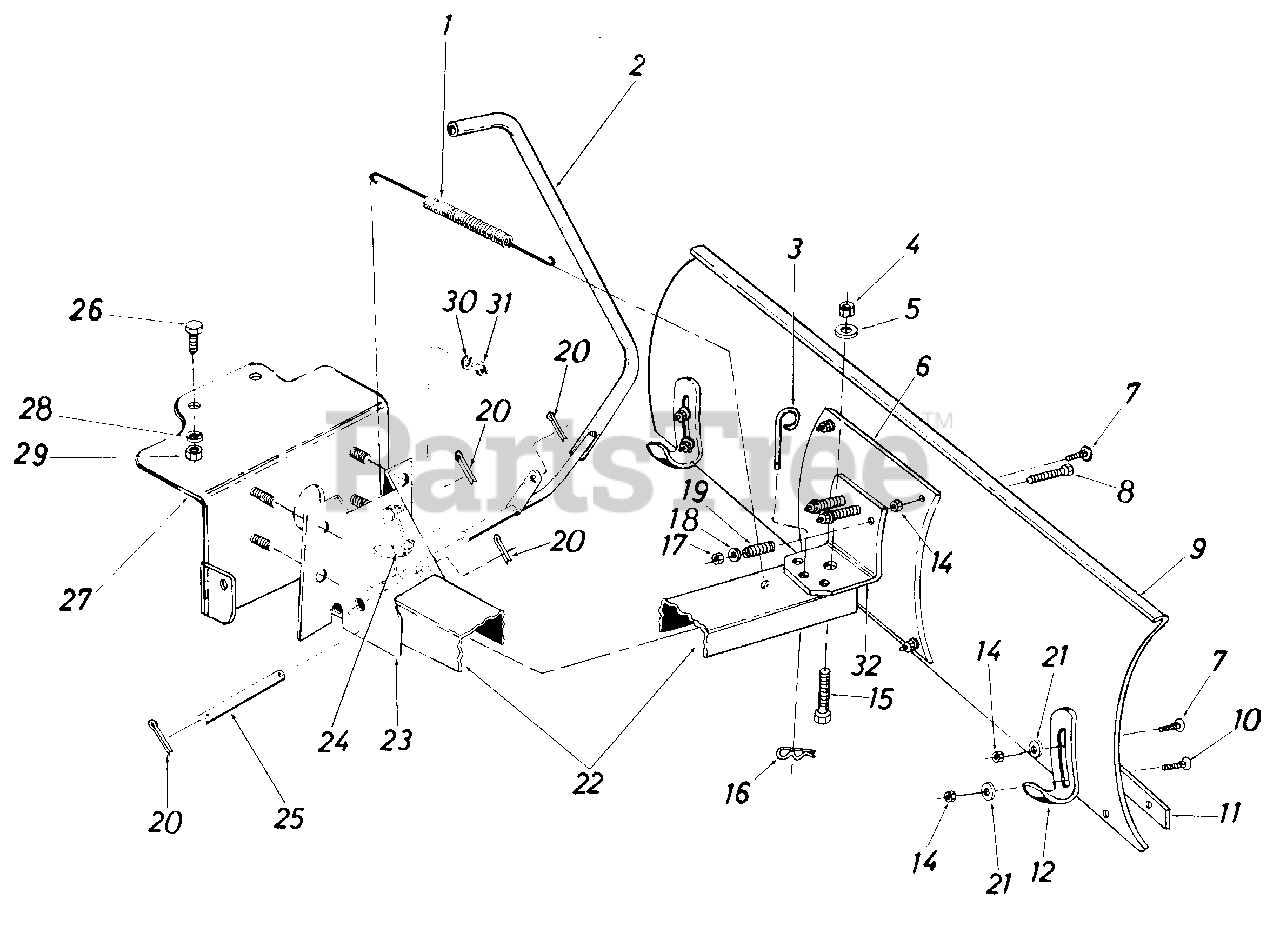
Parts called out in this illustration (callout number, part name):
1	Extension Spring
2	Lift Handle Ass'y.
3	Pivot Lock Pin
4	Hex Cent. L.-Nut 1/2-13 Thd.
5	Fl.-Wash. 17/32 I.D. x 1.25" Lg.
6	Reinforcement Plate
7	Carriage Bolt 5/16-18 x .75" Lg.*
8	Hex Scr. 3/8-16 x 3.75" Lg. Grade 5
9	42" Blade
10	Carriage Bolt 5/16-18 x 1.00" Lg.*
11	42" Wear Plate
12	Shoe Skid
14	Hex Cent. L.-Nut 5/16-18 Thd.*
15	Hex Scr. 1/2'-13 x 1.25" Lg.*
16	Hair Pin Cotter
17	Hex Cent. L.-Nut 3/8-16 Thd.
18	Fl.-Wash. 3/8" I.D.
19	Compression Spring
20	Cotter Pin 1/8" Dia. x 1.00" Lg.*
21	Fl.-Wash. 5/16" I.D.
22	Push Bar Channel
23	Pivot Support Bracket
24	Lift Link
25	Channel Pivot Shaft
26	Hex Scr. 3/8-16 x 1.00" Lg. Grade 5
27	Support Bracket Ass'y.
28	L.-Wash. 3/8 I.D.*
29	Hex Nut 3/8-1 Thd.*
30	L.-Wash. 3/8" I.D.*
31	Hex Jam Nut 3/8-16 Thd.
32	Support Bracket
